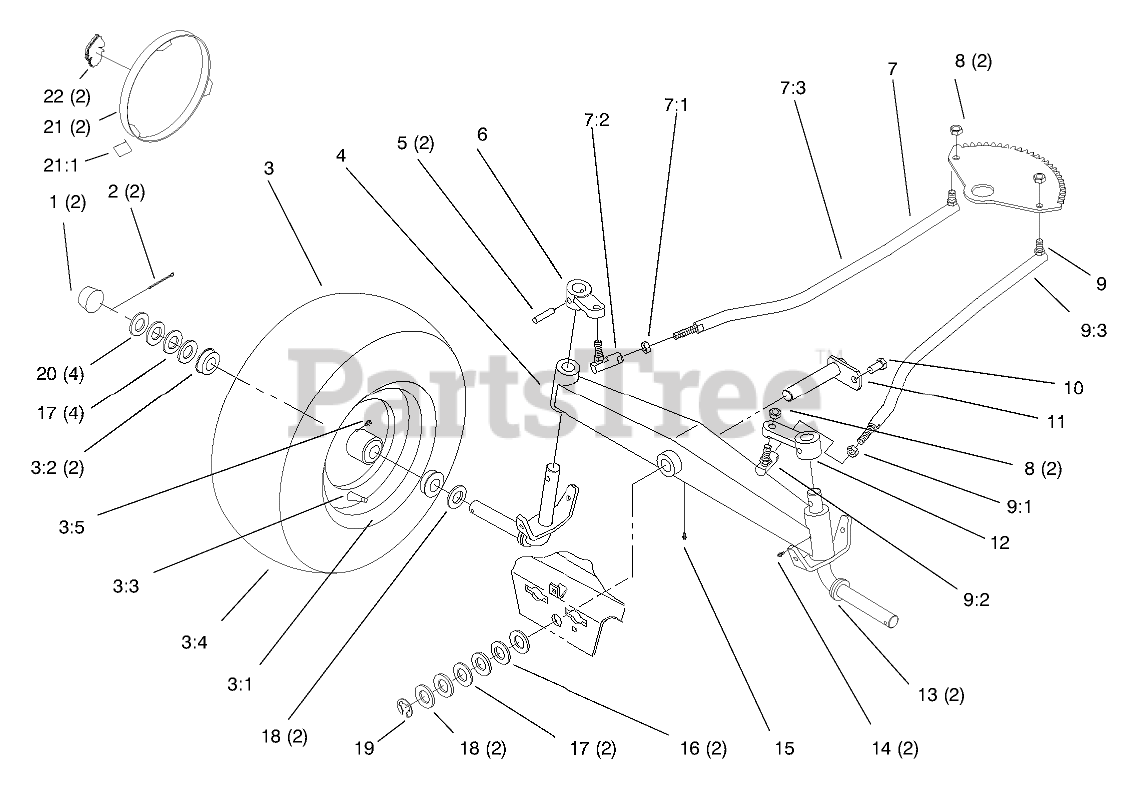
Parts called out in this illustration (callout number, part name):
1	CAP-HUB
2	PIN-COTTER
3	ASM-Wheel & Tire
3:1	Wheel ASM
3:2	BEARING-WHEEL
3:3	VALVE
3:4	Tire (16 x 6.5-8) 2-Ply -2 Wheel Axel
3:5	ZERK-GREASE
4	AXLE-FRONT
6	Arm-Front Spindle
7	LINKAGE-STEERING, RH
7:1	Nut-Hex Jam
7:2	BALL-JOINT
7:3	Ball Link ASM
9	LINKAGE-STEERING, LH
9:1	Nut-Hex Jam
9:2	BALL-JOINT
9:3	Ball Link ASM
10	SCREW-HWH, TAPTITE
11	PIN-AXLE
12	Arm-Front Spindle
13	SPINDLE
14	FITTING-GREASE
15	FITTING-LUBE, 45 DEG
16	Washer
17	WASHER
18	WASHER-SHIM
19	E-RING
20	WASHER-PLAIN
21	SILVER HUB CAP/LOGO ASM
21	HUBCAP - 8"
22	LOGO - HORSEHEAD
